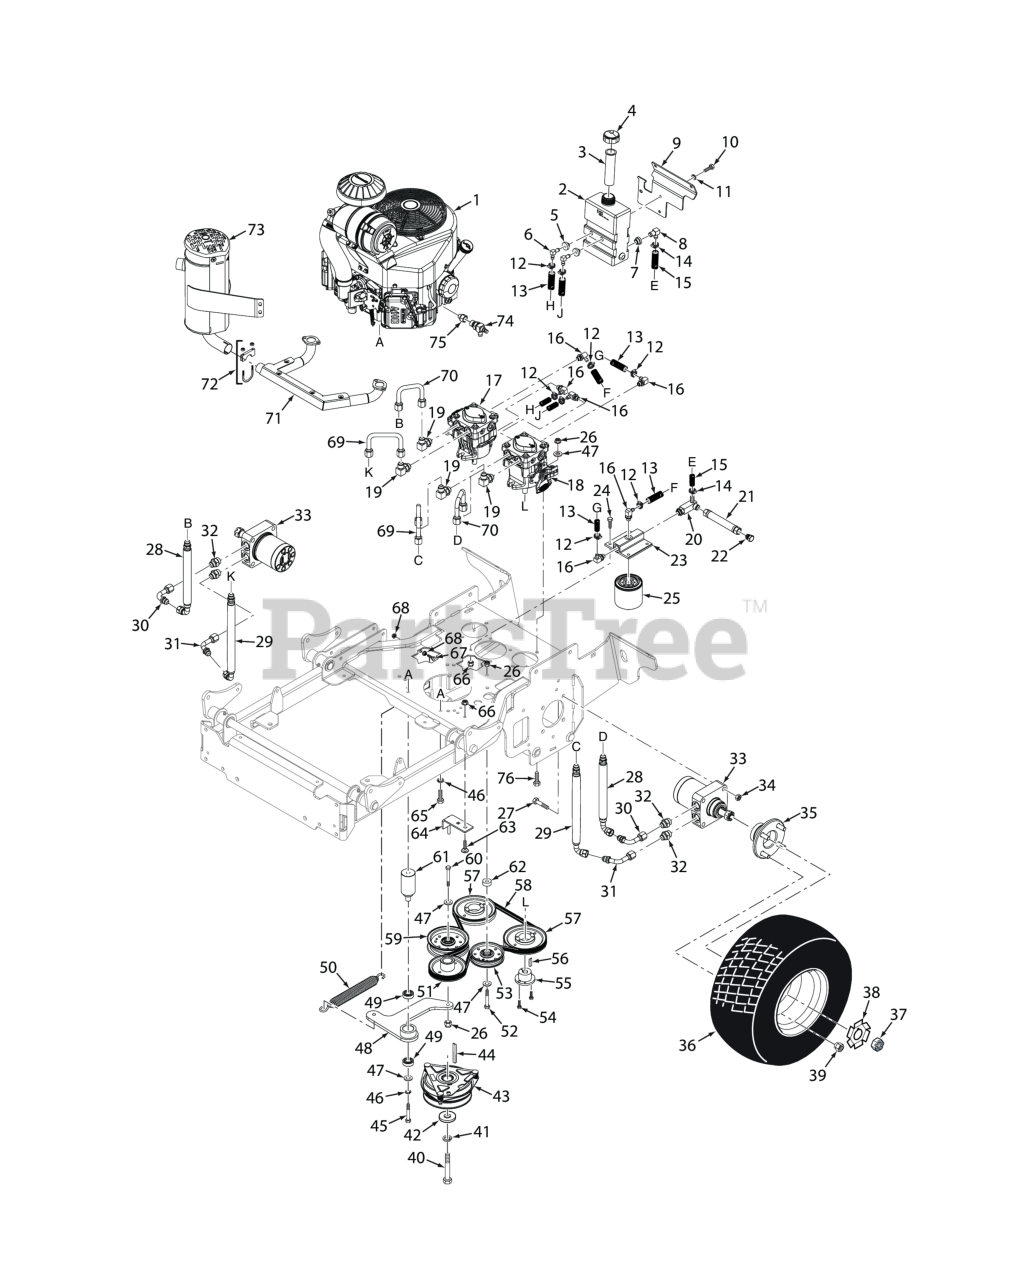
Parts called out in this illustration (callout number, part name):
1	Engine, 16 HP Kawasaki FX (32)
2	Hydro Tank Assy., SVRII
3	Insert, Filler Neck
4	CAP, HYDRAULIC TANK
5	Bushing, 0.56" Dia. Viton
6	Elbow, 90 Degree, 9/16-18 JIC x 9/16 O-Ring
7	Bushing, 0.78" Dia. Viton
8	Fitting, 90 Degree - 1/2" Hose
9	Bracket, Hydro Tank Mounting
10	BOLT, SERRATED FLANGE HEX HEAD 5/16-18 X 3/4"
11	Lockwasher, 5/16 (.317 x .586 x .078) Helical Spring
12	Clamp, .69" Max. / .25" Min. Dia.
13	Hose, 3/8" ID - 10-1/4" Long (Order By The Inch)
14	Clamp, Cable 3/4" I.D.
15	Hose Assembly, 1/2" ID (Oil Reservoir to Filter Base)
16	Elbow, 90 Degree - 9/16" O-Ring x 3/8" Hose
17	Pump, LH - 10cc (36 Only)
18	Pump, RH - 10cc (36 Only)
19	Elbow, 90 Degree 3/4-16 JIC x 3/4-16 O-Ring
20	Tee, 3/4" O-Ring
21	Drain Hose Assy.
22	Plug, JIC 3/4-16 UNF
23	Filter Head Assembly
24	BOLT, SERRATED FLANGE HEX HEAD 5/16-18 X 3/4"
25	OIL FILTER, SPECIAL
26	HEX NUT, ELASTIC STOP LOCK, 3/8-16
27	Bolt, Hex Hd. 1/2-13 x 2-1/2" (lower)
28	Hose Assy., 11-1/4"
29	Hose Assy., 13-1/4"
30	Tube Assy., 1/2 x 2 x 2"
31	Tube Assy., 1/2 x 2 x 3-1/4"
32	TUBE UNION, 3/4-16 JIC TO 7/8-14 "O" RING
33	Wheel Motor
34	Locknut, Hex 1/2-13 Center Lock
35	Bolt, Serr. Flange 1/2-20 x 4.563"
36	Wheel Assy., 20 x 6.5 - 10 (32)
37	HEX CASTLE NUT, 3/4-28 UNEF
38	Lock Washer, Wheel Motor
39	Wheel Nut, 1/2-20 x 13/16
40	Bolt, Hex Head 7/16-20 x 2-1/4" w/Patch (Kawasaki)
41	Lockwasher, 7/16� Spring
42	Flatwasher, 7/16-.469 x 1.75 x .25 (48, 52)
43	Clutch w/Tag GT2.5-FE02 (48 / 52)
44	Key, 1/4 x 1/4 x 3-1/2"
45	Capscrew, Hex Head 3/8-16 x 3-3/4"
46	Lockwasher, 3/8" Spring, Kawasaki FX / FT & FT-EFI / B&S 32BV
47	Flatwasher, 3/8 (.391 x .938 x .105 HD) Grade 8
48	Idler Arm Assy., Pump Drive
49	BEARINGS, BALL, NEUTRAL RETURN
50	Spring, Transmission Idler
51	Pulley, 4-3/4" OD - 1.125 Bore
52	Bolt, Hex Head 3/8-16 x 2-1/4" - 61"
53	Pulley, Idler 4� Dia.
54	Bolt, Hex Head 1/4-20 x 1" Grade 8 Black
55	Hub, Tapered, 15mm Bore
56	KEY, 5 MM X 5 MM X 25 MM
57	Pulley, 5.45 OD - Tapered Bore"
58	Belt, Pump Drive - SVRII-36
59	Pulley, 4" Dia. Idler
60	Bolt, Hex Head 3/8-16 x 2-1/4" - 61"
61	Pivot, Idler
62	Spacer, Idler Pulley - SFZ61
63	Bolt, 5/16-18 x .75 RHSN Carriage
64	ANTI-ROTATION WLMT, SVRII
65	Bolt, Hex Head 3/8-16 x 1-1/4", Kawasaki FX / FT & FT-EFI
66	Nut, Serrated Flange 5/16-18 (Right Front Engine Mounting, Briggs and Kohler Only)
67	Bolt, Hex Head 3/8-16 x 1-1/2" Grade 8 Black
68	NUT, 3/8-16 SERRATED FLANGE HEX HEAD
69	1/2" U-Tube Assembly, 4" Wide
70	Tube Assy., 1/2 x 2" Wide
71	Exhaust Manifold, 16 HP Kawasaki FX
72	Muffler Clamp
73	Muffler, Kawasaki (FS481, FS541, FS600)
74	Oil Drain, 35BV & 37BV-EFI - Briggs & Stratton
75	FITTING, M14 FEMALE TO M20 MALE
76	Bolt, Hex Head 3/8-16 x 1-1/2" B&S 32BV
